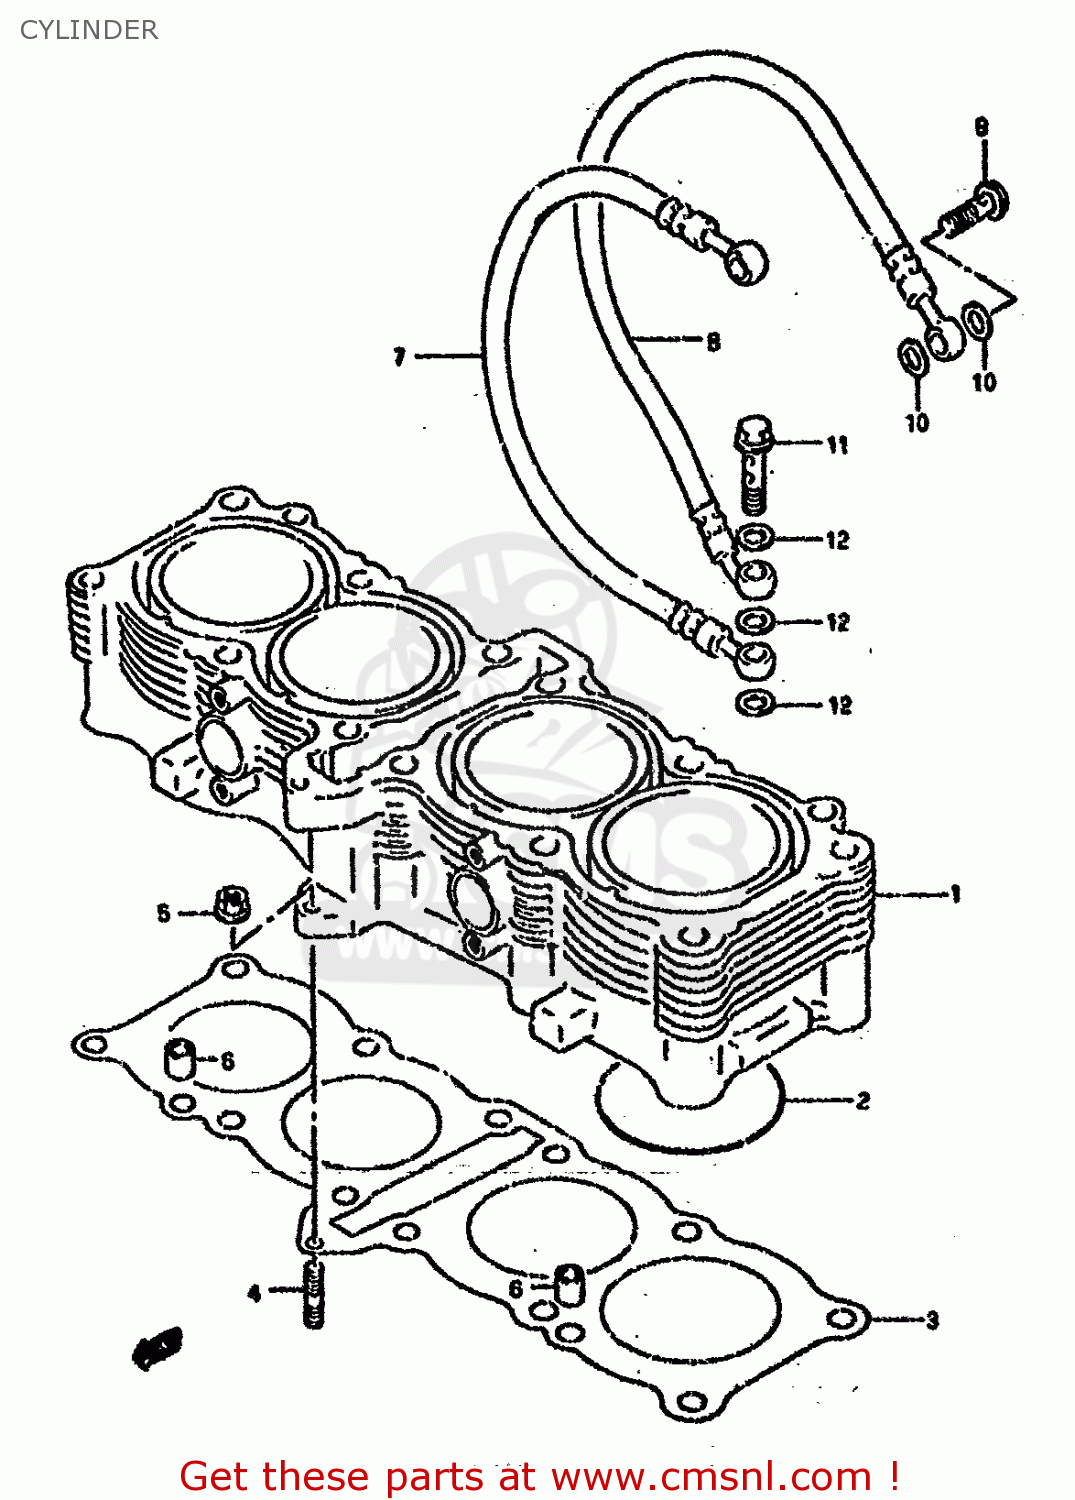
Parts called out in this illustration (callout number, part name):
1	CYLINDER
2	O-RING
3	GASKET,CYLINDER
4	STUD,M6X1X32
5	NUT
6	PIN
7	HOSE,OIL,R
8	HOSE,OIL,L
9	BOLT,OIL PIPE UNION,NO
10	GASKET(8.2X14X1) (NAS)
11	BOLT,OIL PIPE UNION,NO
12	WASHER(10X15X1.5)
